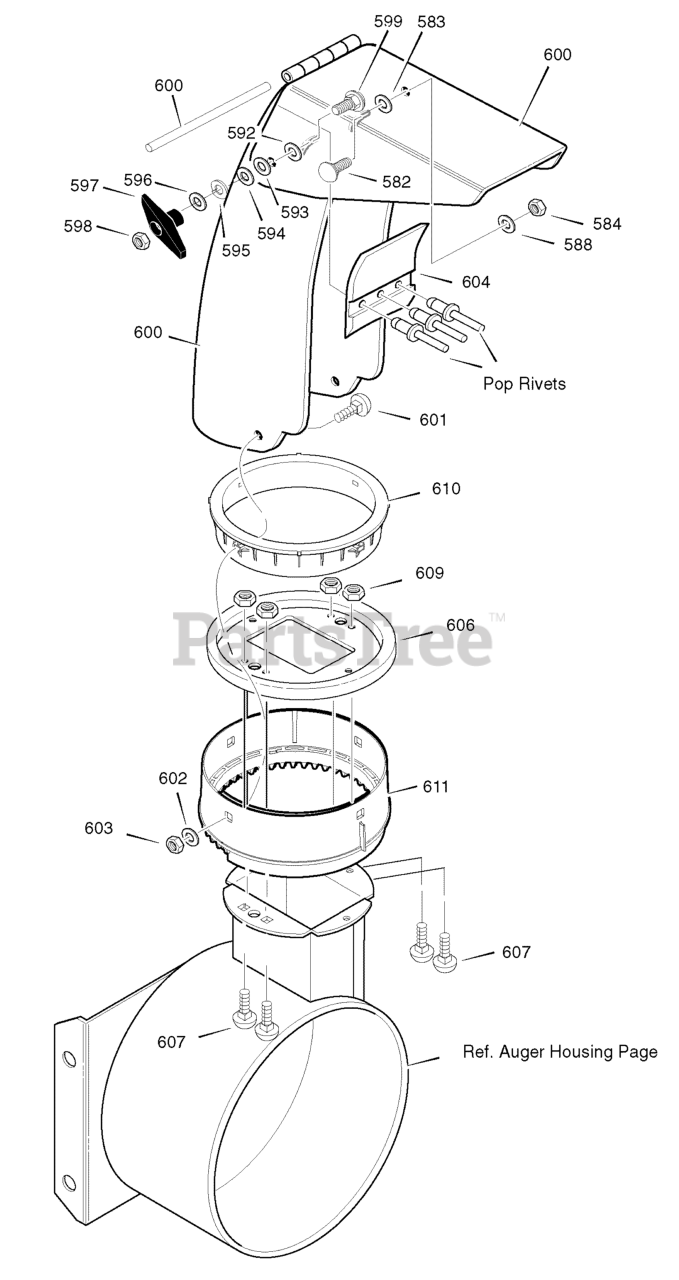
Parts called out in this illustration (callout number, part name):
582	BOLT, CARRIAGE 5/16-18 X.75
583	WASHER, PLASTIC
584	NUT, 5/16-18 REGHEX NYLOCK
588	WASHER, PLASTIC
592	WASHER, PLASTIC
593	WASHER, PLASTIC
594	WASHER, FLAT
595	WASHER, SPLIT
596	WASHER, FLAT
597	KNOB, T 3.00
598	NUT, 5/16-18 REGHEX
599	BOLT, 5/16-18X1.00
600	CHUTE ASSEMBLY
601	CARRIAGE BOLT, 5/16-18 x 1
602	WASHER, FLAT
603	NUT, 5/16-18 HEXNYL
604	FLAP, CHUTE
606	CHUTE COLLAR
607	SCREW, 1/4-20 X 0.75
609	NUT, 1/4-20 HEX NYLOCK
610	RETAINER RING INNER
611	RETAINER RING OUTER
